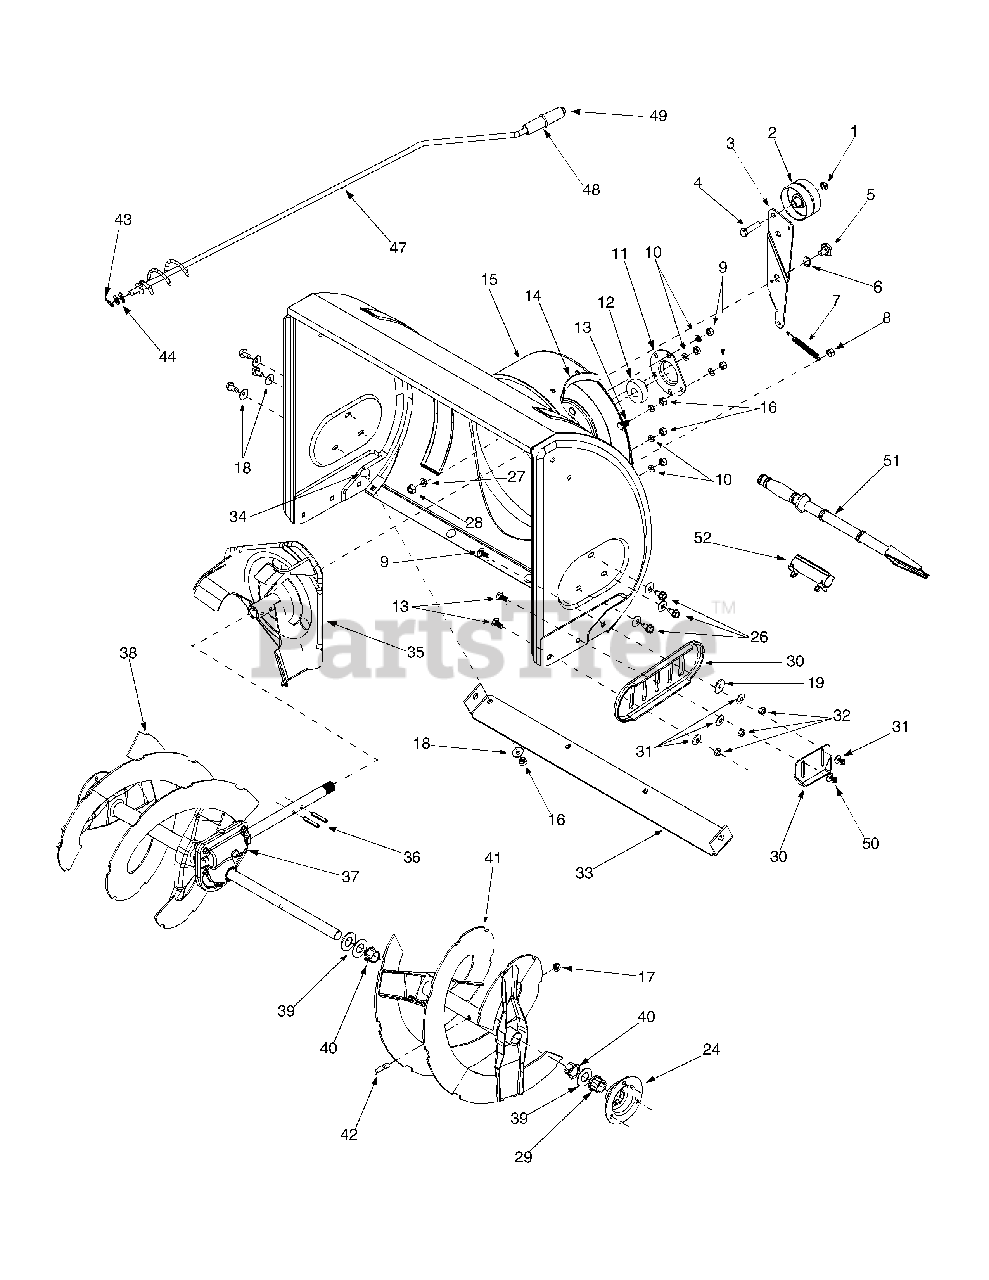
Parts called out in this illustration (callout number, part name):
1	Lock Jam Nut 3/8-24
2	Flat Idler
4	Hex Cap Screw 3/8-24 x 1.50
5	Shoulder Screw
6	Wave Washer
7	Extension Spring
8	Hex Nut 5/16-18
9	Carriage Bolt, 5/16-18 x 1.00
10	Lock Washer 5/16
11	Bearing Housing
12	Ball Bearing
13	Carriage Bolt, 5/16-18 x .75
17	Lock Nut 5/16-18
18	Belleville Washer
19	Flat Wshr, .344ID x 1.125 OD
26	Hex Screw 5/16-18
27	Lock Washer 3/8
28	Hex Nut 3/8-16
29	Hex Flange Bearing
31	Bell Washer
32	Hex Nut 5/16-18
34	Carriage Bolt 5/16-18 x .62
37	28" Gear Ass’y
39	Flat Washer
40	Flange Bushing
42	Shear Bolt 5/16-18 x 1.5
43	Hairpin Clip
44	Flat Washer
47	Chute Crank
48	Chute Crank Knob
49	Push Cap
50	Hex Nut 5/16-18
51	Clean-Out Tool
52	Clean-Out Tool Mount
